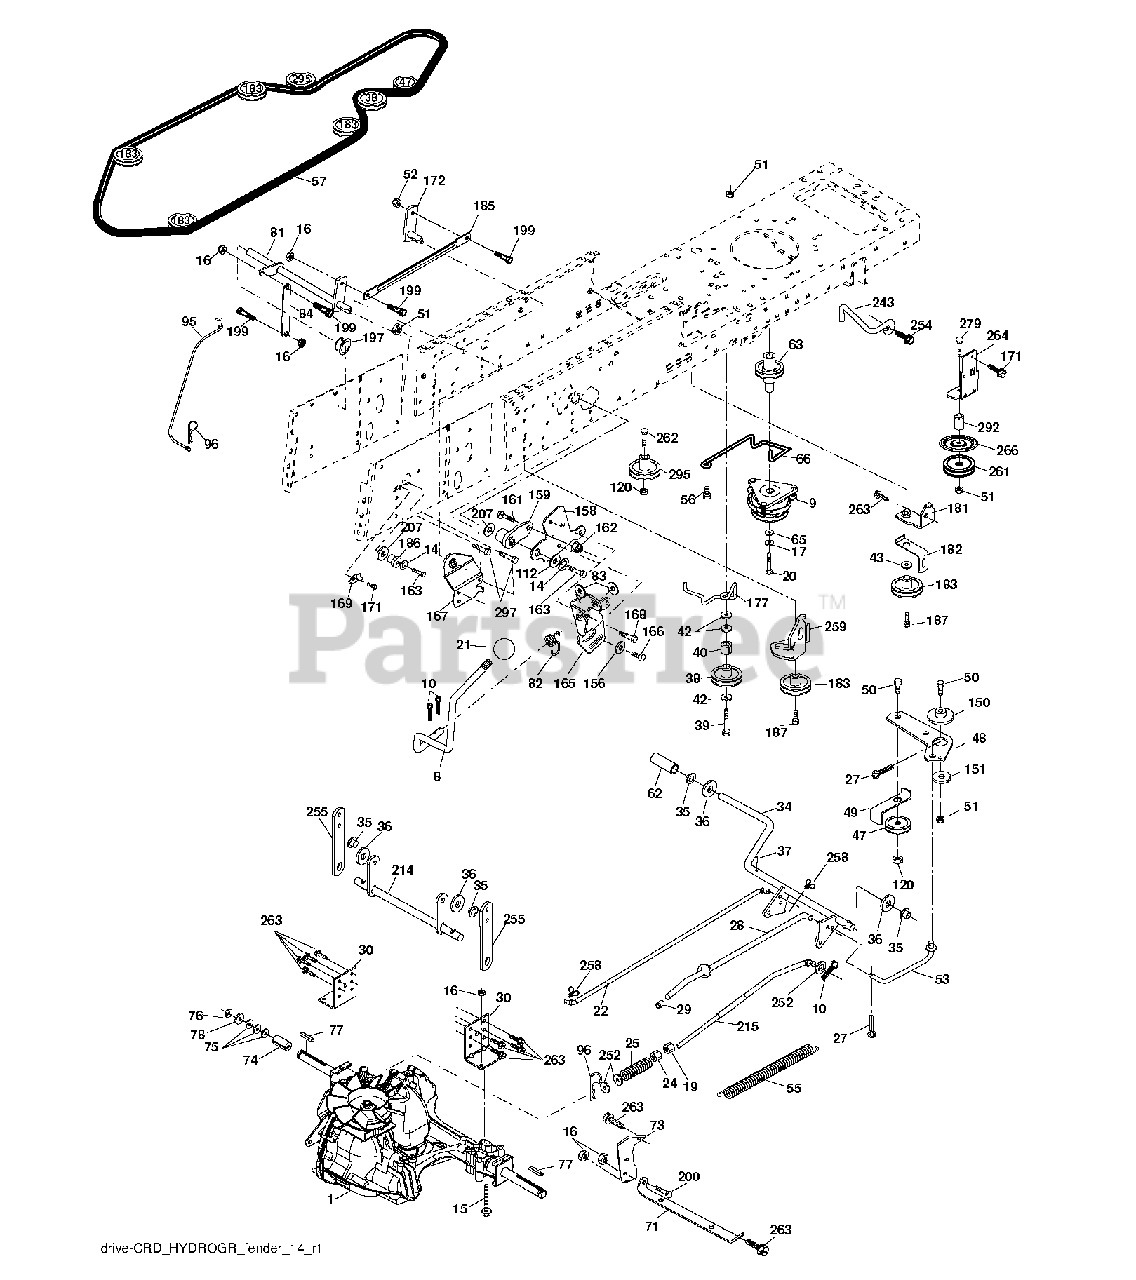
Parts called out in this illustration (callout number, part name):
8	ROD SHIFT FENDER ADJUST LT
10	PIN COTTER
14	LOCKWASHER
15	BOLT HEX 5/16-18 GR 5
16	NUT.71038.31-18.HEX.NYLOCK
17	LOCKWASHER
19	NUT
20	BOLT HEX 7/16-20X4-1/4"
21	PISTOL KNOB
24	NUT
27	COTTER PIN
28	ROD, PARKING BRAKE
29	PLUNGER CAP
30	BRKT, TRNSXLE MNT 20"
34	SHAFT, FOOT PEDAL
35	BEARING.NYLON
36	WASHER LT
37	DRIVE PIN
38	PULLEY.FLAT
42	WASHER
47	IDLER PULLEY
48	BELLCRANK, CLUTCH
49	RETAIN BELT
50	BOLT.3/8-16X1.50
51	LOCKNUT
52	LOCKNUT
53	LINK.CLUTCH.7.66.2005
55	SPRING, RETURN LT
56	SCREW.3/8-16
62	PEDAL COVER T
66	KEEPER BELT ENGINE
71	STRAP TORQUE LH HYDRO
73	STRAP TORQUE RH HYDRO
74	SPACER AXLE
76	E-RING LT
77	SQUARE KEY
81	SHAFT ASSY
82	SHIFT SPRING
83	WASHER
96	RETAINER M
112	WASHER LT
120	NUT LOCK FLG 3/8-16 UNC
150	BUSHING.BELLCRANK.GRD.DR
151	WASHER 12/32X2X10GA
156	WASHER.SRRTD.5/16
158	BRACKET
159	HUB.SHIFT
161	BOLT
162	NUT.CROWNLOCK.1/4
165	RP BRACKET
167	BRACKET
168	BOLT.SHOULDER.5/16-18X
169	PLATE.FASTENING.CROSS.SHAFT
187	BOLT.5/16-18X1.25
197	NYLINER SNAP 5/8" ID
199	BOLT SHOULDER 5/16-18 UNC
200	BOLT
207	WASHER NYL
243	BRACKET, ANTI-ROTATION
254	SCREW 3/8-16X1
258	CLIP RETAINER
261	FLAT IDLER PULLEY
263	SCREW, 3/8-16X3/4
279	BOLT
295	PULLEY IDLER COMPOSITE
297	SCREW LT.3/8-46X5/8
